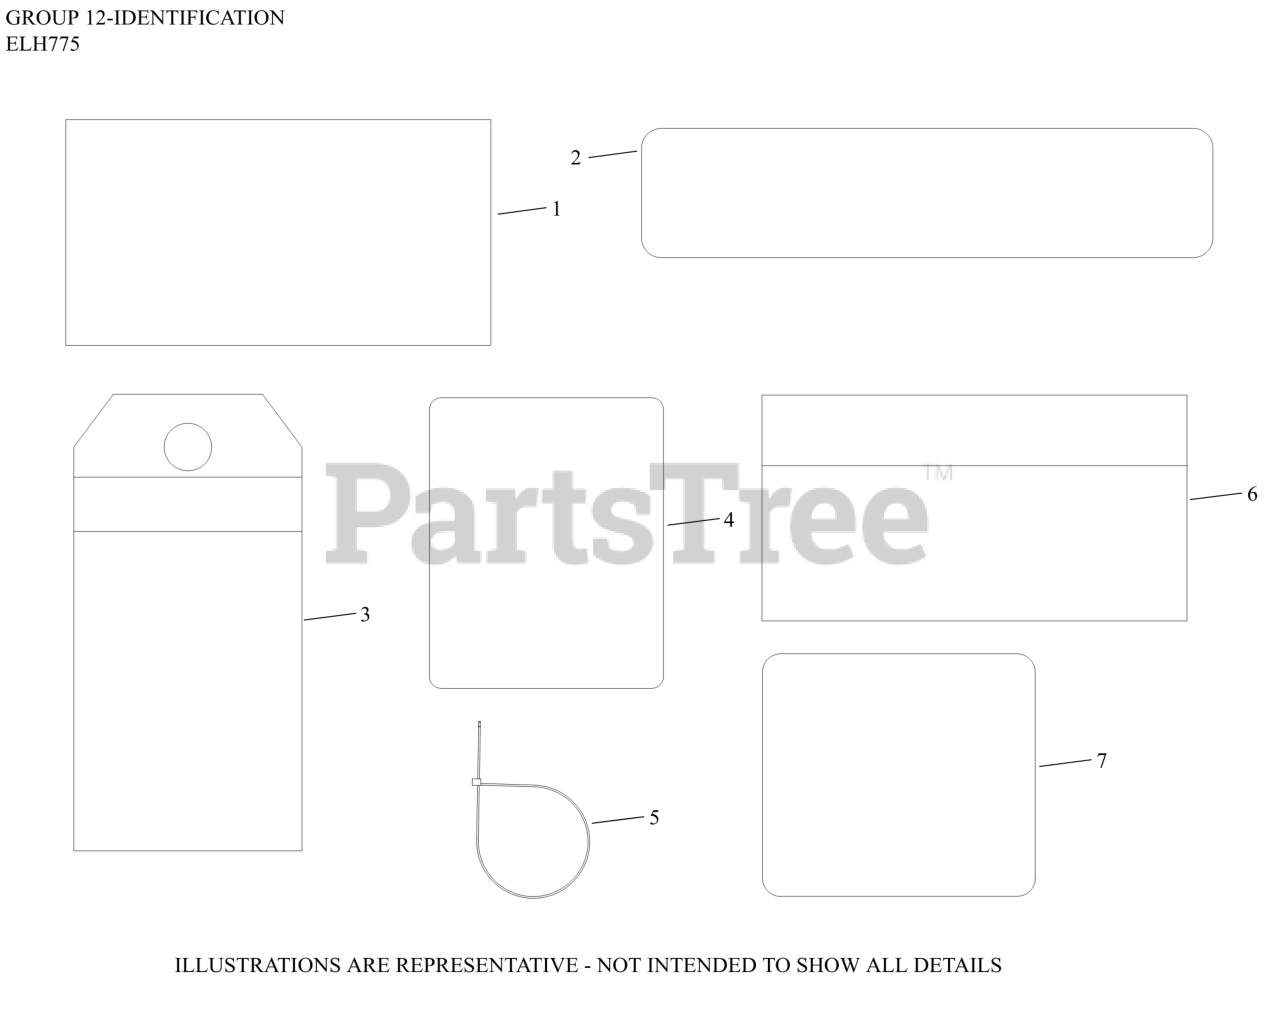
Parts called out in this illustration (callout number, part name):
1	DECAL, ROTATING FAN WARNING-DISC.
2	DECAL AEGIS, ENGINE DISPLACEMENT
3	TAG, HANG (NO COOLANT)
4	LABEL, CLEAR LAMINATION
6	DECAL, COOLANT LEVEL
7	DECAL, WARNING
